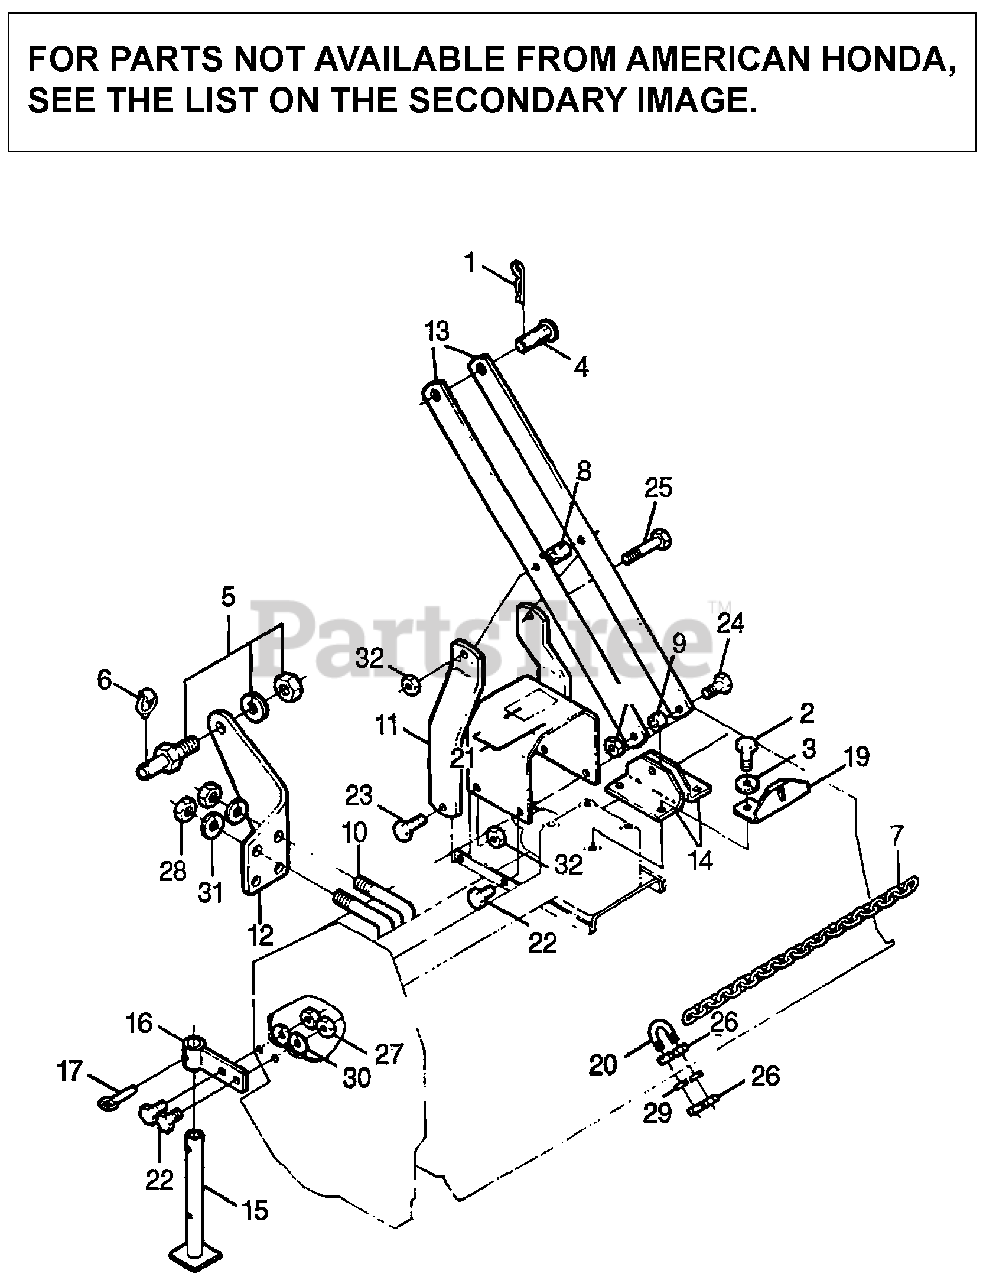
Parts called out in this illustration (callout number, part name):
2	SCREW, CAP (10X1.5X22)
3	WASHER, LOCK (10MM)
5	PIN, LIFT ARM
6	PIN, LINCH
8	BUSHING, TOP LINK (1-1/16") (NOT AVAILABLE)
9	BUSHING, MAST (NOT AVAILABLE)
10	U-BOLT (NOT AVAILABLE)
12	LUG, L. HITCH
12	LUG, R. HITCH
13	MAST, TOP LINK
15	WELD, PARKING STAND (NOT AVAILABLE)
16	WELD, STAND SECURING
18	DECAL, CAUTION (NOT AVAILABLE)
19	RETAINER, CHAIN (NOT AVAILABLE)
20	U-BOLT (1/4") (20 UNC)
21	SHIELD ASSY. (NOT AVAILABLE)
